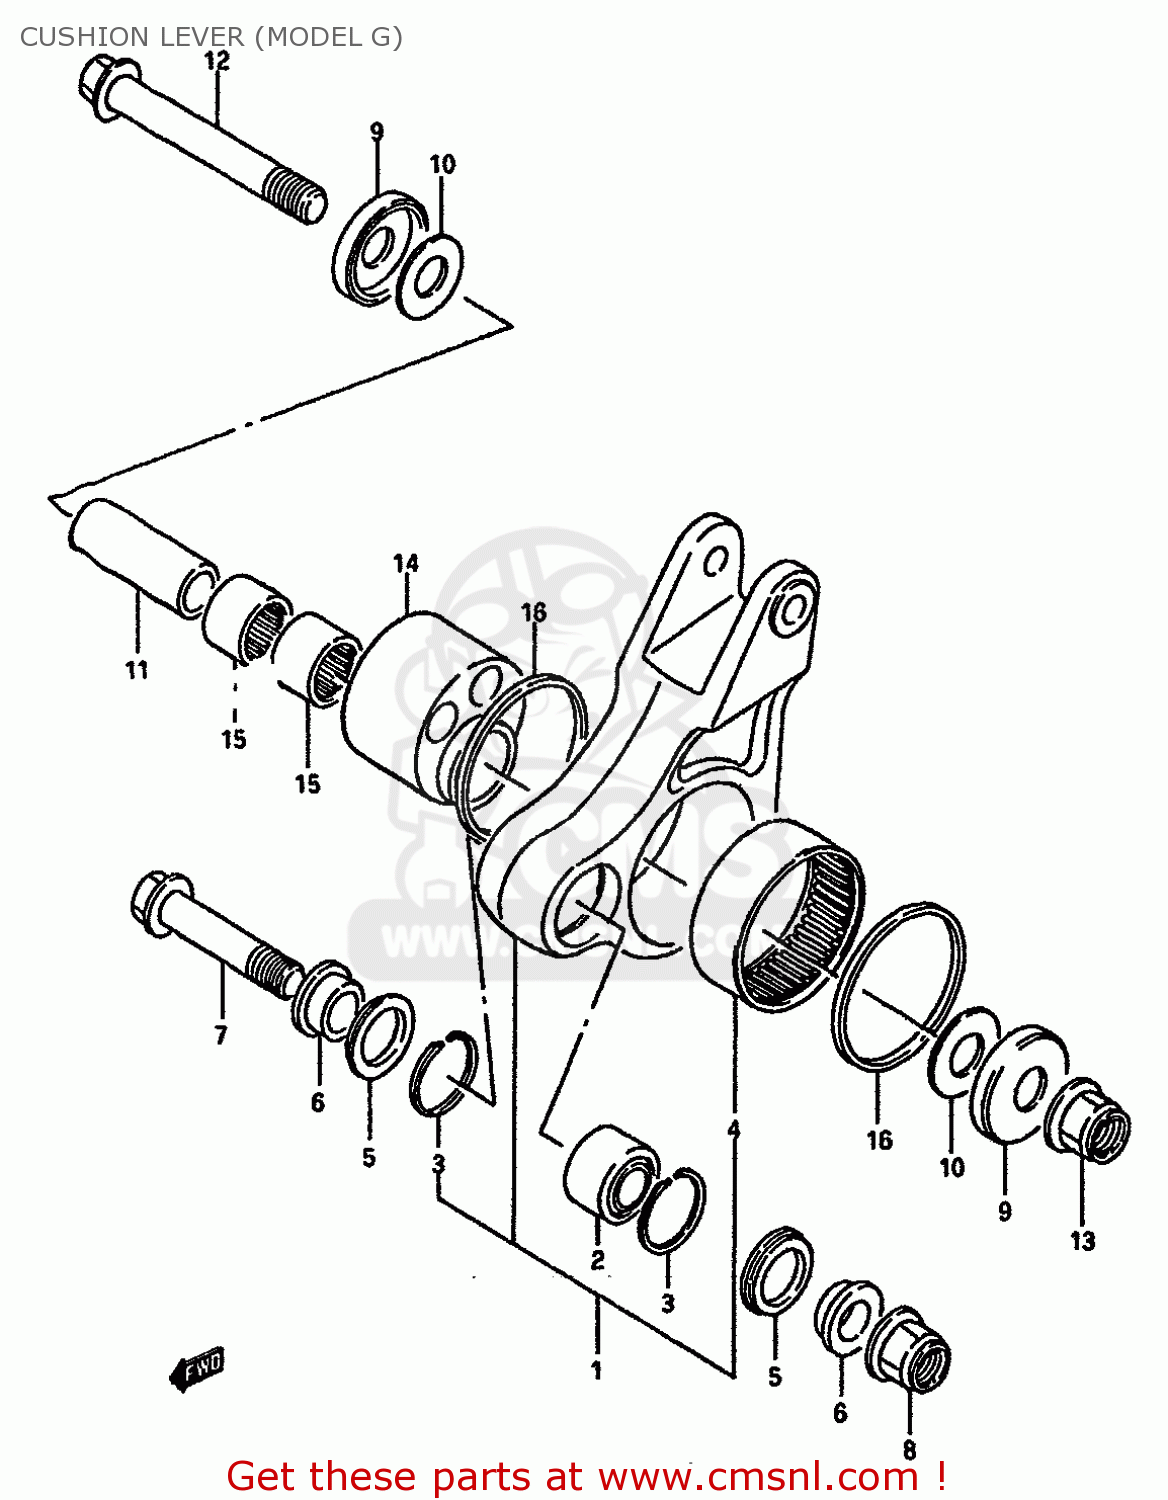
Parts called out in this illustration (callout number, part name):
1	LEVER SET,REAR CUSHION
2	SPHERICAL BEARING (14X3)
3	RING,STOPPER
4	BEARING 55X63X25
5	DUST SEAL,REAR CUSHION,LEFT
6	SPACER,REAR CUSHION LEVER
7	BOLT,RR CUSHION LEVER FR
8	NUT
9	DUST SEAL,RR C
10	WASHER
11	SPACER,RR CUSHION LEVER CTR
12	SHAFT,RR CUSHION LEVER
13	NUT
14	SPACER,RR CUSHION ECCENTRIC
15	BEARING
16	SEAL,REAR CUSHION LEVER
